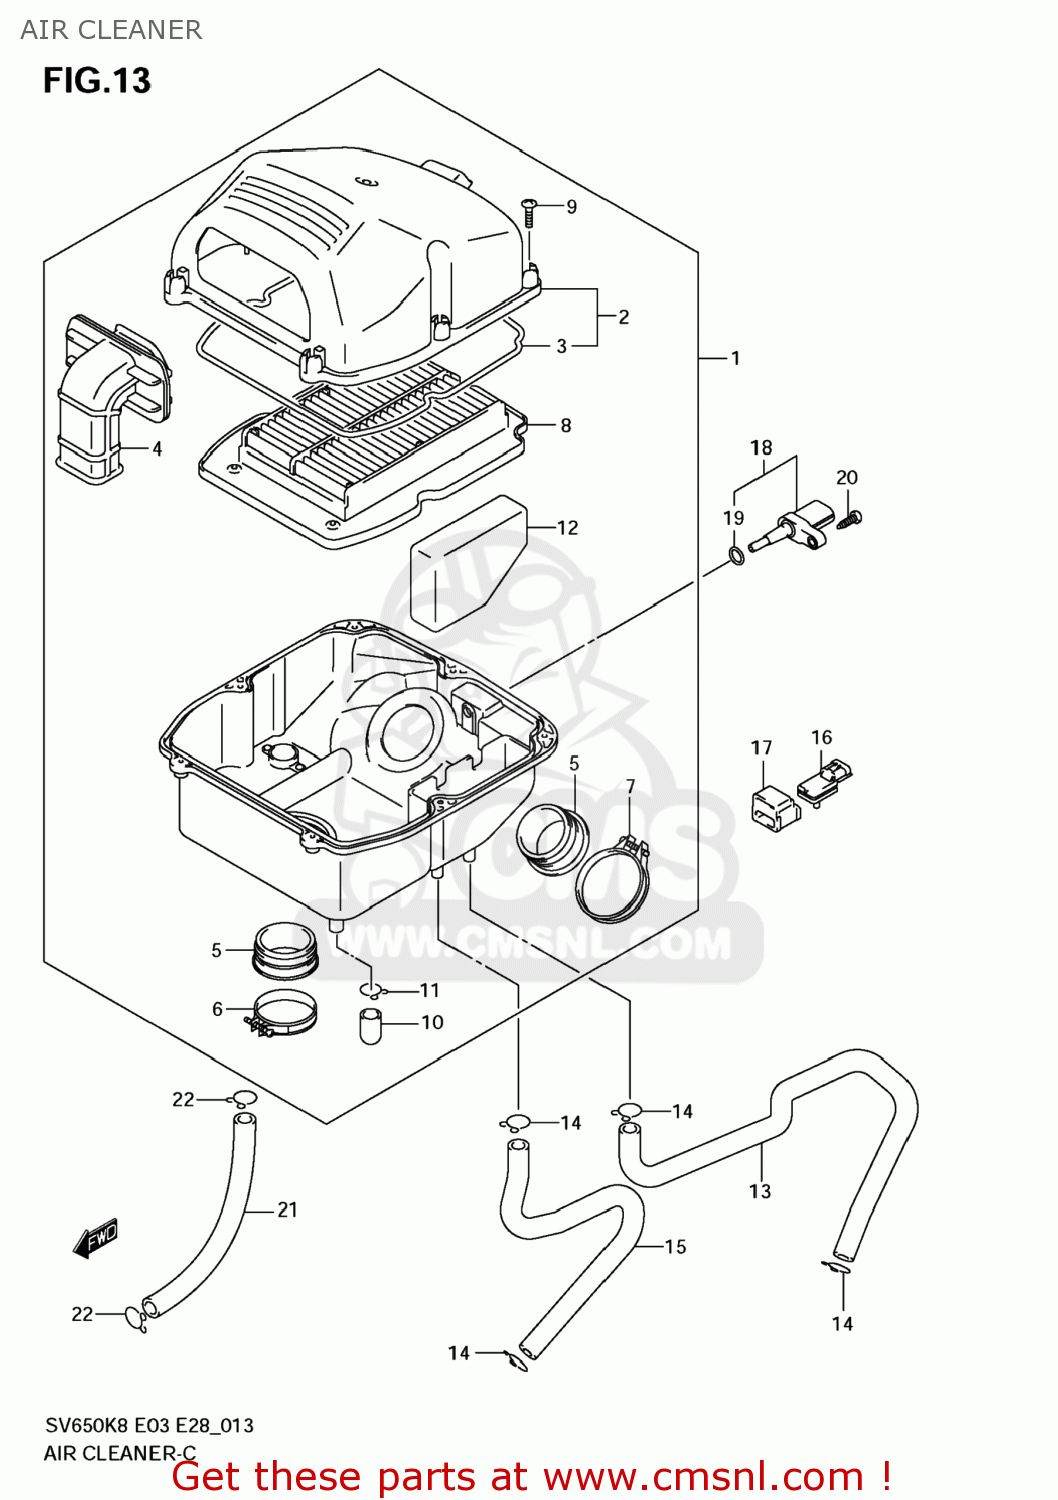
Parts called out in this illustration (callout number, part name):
1	CLEANER ASSY,AIR
2	CAP,AIR CLEANER
3	GASKET (NAS)
4	TUBE,INLET
5	TUBE,OUTLET
6	CLAMP
7	CLAMP
8	FILTER
9	SCREW
10	PLUG
11	CLIP
12	FILTER,BREATHER
13	TUBE,BREATHER CRANKCASE
14	CLIP
15	TUBE,BREATHER CYLINDER
16	SENSOR,PRESSURE
17	HOLDER,SENSOR
18	SENSOR,AIR TEMP
19	O RING
20	SCREW
21	HOSE,ISC CLNR
22	CLIP
